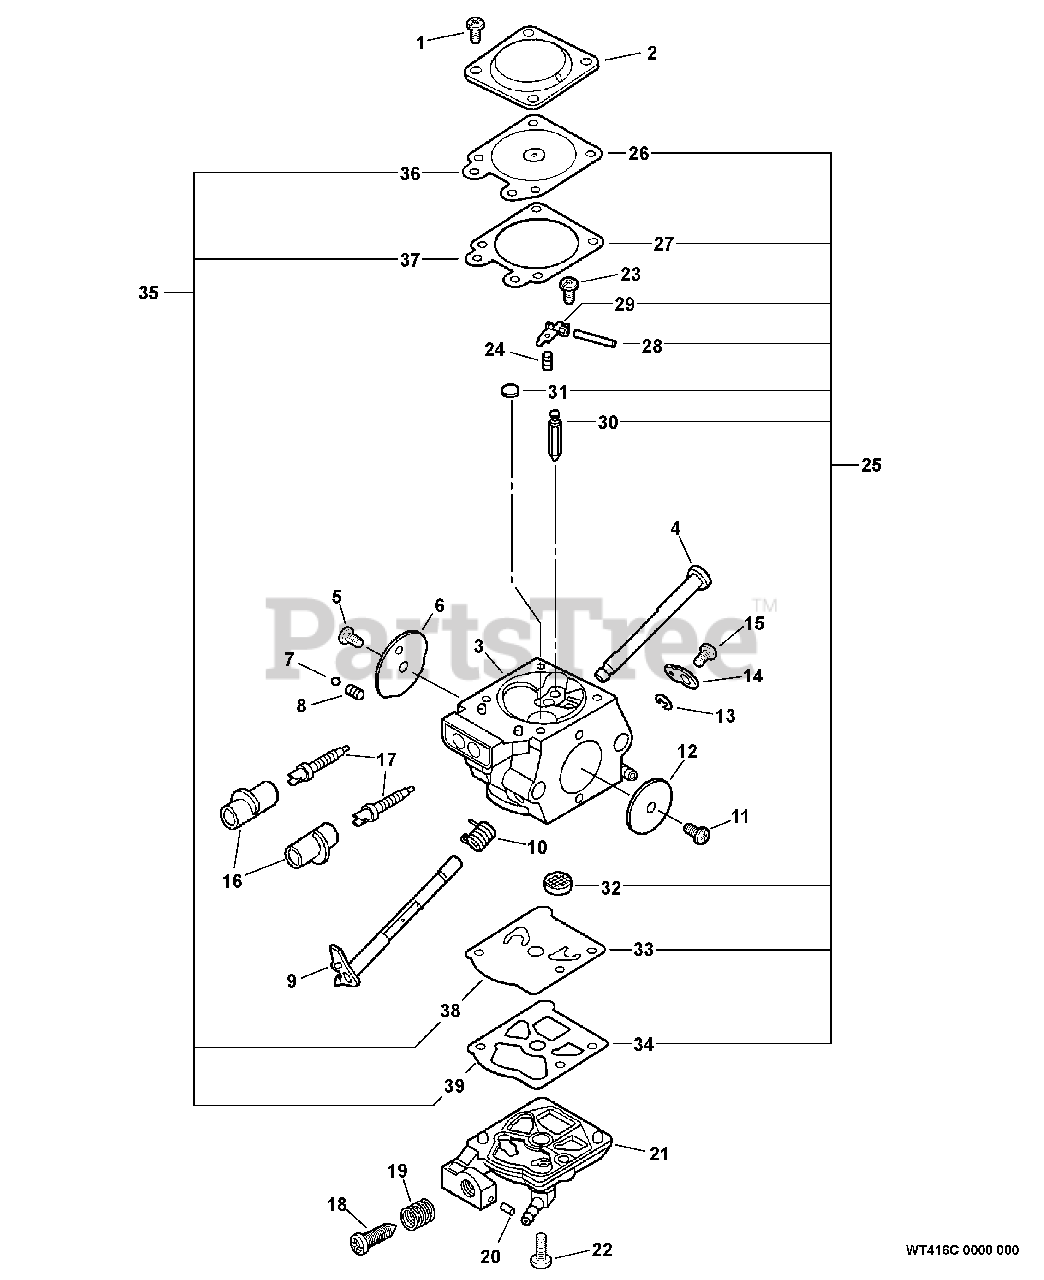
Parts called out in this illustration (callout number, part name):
2	COVER, METERING DIAPHRAGM
3	BODY, CARBURETOR
4	SHAFT, CHOKE
5	SCREW, VALVE
6	VALVE, CHOKE
7	BALL, CHOKE FRICTION
9	SHAFT, THROTTLE
10	SPRING, THROTTLE RETURN
11	SCREW, VALVE
12	VALVE, THROTTLE
14	LEVER, THROTTLE
15	SCREW, VALVE
16	CAP, LIMITER
17	NEEDLE, MIXTURE
18	SCREW, IDLE ADJUST
19	SPRING, IDLE ADJUST
20	PLUG, FRICTION
21	COVER, FUEL PUMP
23	SCREW, METERING LEVER PIN
24	SPRING, METERING LEVER
25	REPAIR KIT, CARBURETOR
26	DIAPHRAGM, METERING
27	GASKET, DIAPHRAGM
28	PIN, METERING LEVER
29	LEVER, METERING
30	VALVE, INLET NEEDLE
31	PLUG, WELCH
32	STRAINER
33	DIAPHRAGM, PUMP
34	GASKET, PUMP
35	GASKET / DIAPHRAGM KIT
36	DIAPHRAGM, METERING
37	GASKET, DIAPHRAGM
38	DIAPHRAGM, PUMP
39	GASKET, PUMP
